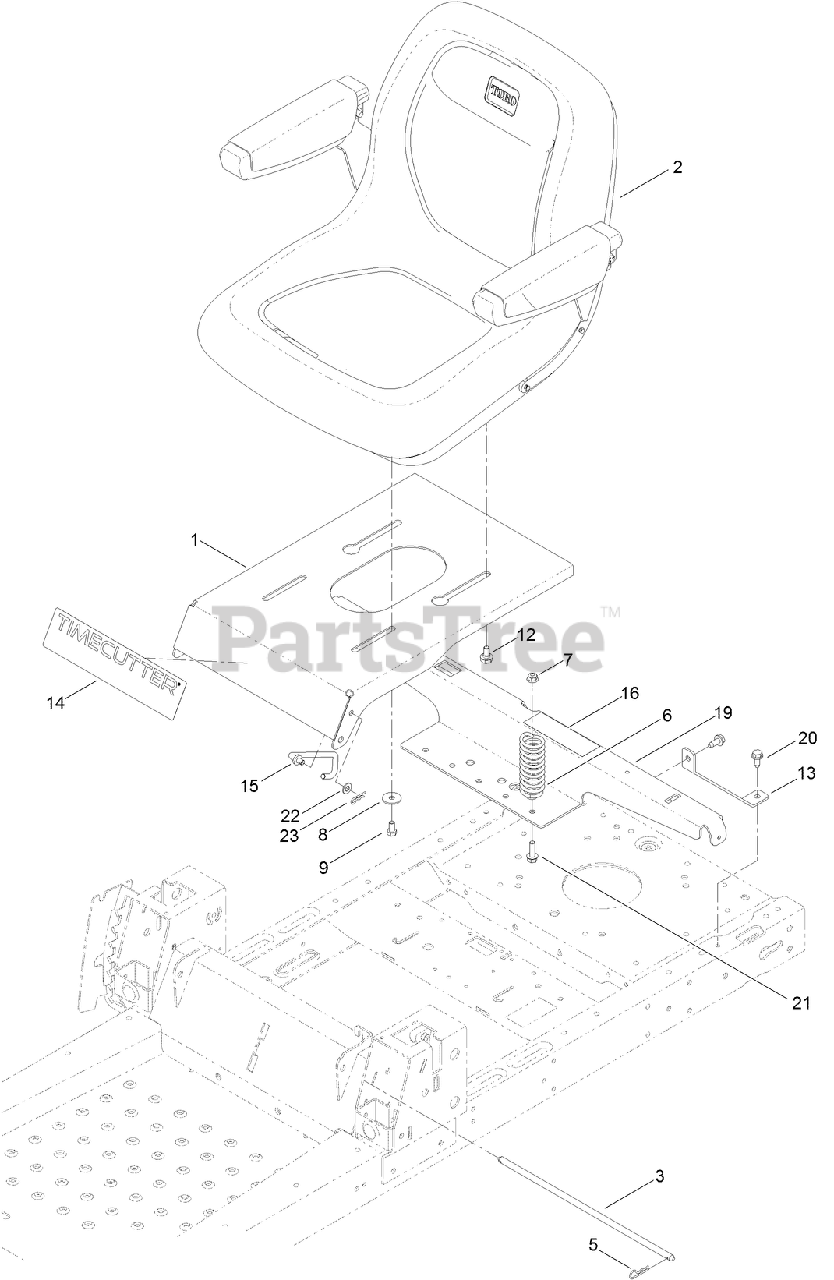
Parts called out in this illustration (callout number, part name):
2	SEAT-18 INCH
3	ROD-PIVOT, NARROW
5	PIN-COTTER
6	SPRING-COMPRESSION
7	NUT-HF, NI
8	WASHER-PIVOT
9	SCREW-HH
12	BOLT-SHOULDER,HFH
13	SUPPORT-TANK, REAR
14	DECAL-TIMECUTTER
15	STOP-SEAT
16	DECAL-SERVICE, CE
19	SUPPORT-POD
20	SCREW-HWHTF
21	SCREW-HHF
22	WASHER-PLAIN
